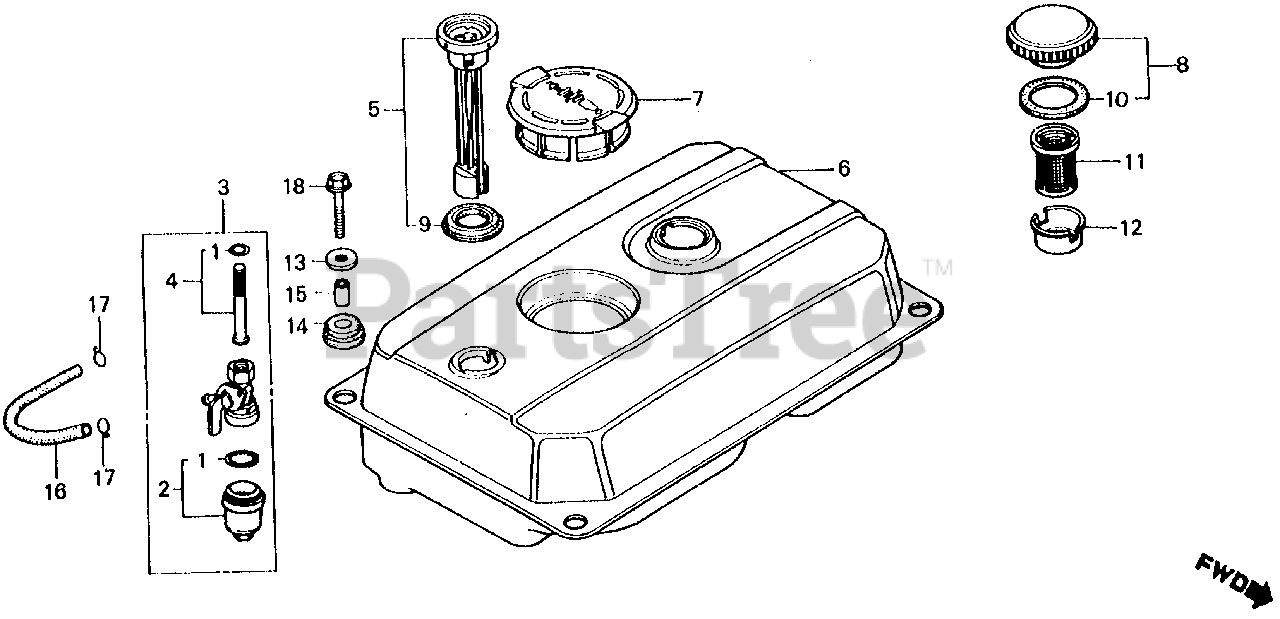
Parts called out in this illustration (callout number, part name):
1	GASKET SET, PETCOCK (CONTAINS 1 LARGE & 1 SMALL. USE AS NEEDED)
2	CUP, FUEL STRAINER
3	PETCOCK ASSY.
4	SCREEN SET
5	METER, FUEL
6	TANK, FUEL *NH31* (MCKINLEY WHITE)
7	CAP, SPARK PLUG HOLE
8	CAP, FUEL FILLER
9	GASKET C, FUEL METER
10	GASKET, FUEL FILLER CAP
11	FILTER, FUEL
12	HOLDER, FUEL FILTER
13	WASHER, TANK RUBBER
14	CUSHION, TANK RUBBER
15	COLLAR, TANK RUBBER
16	BULK HOSE, FUEL (4.5X3000) (4.5X105)
17	CLIP, TUBE (B8)
18	BOLT, FLANGE (6X25)
